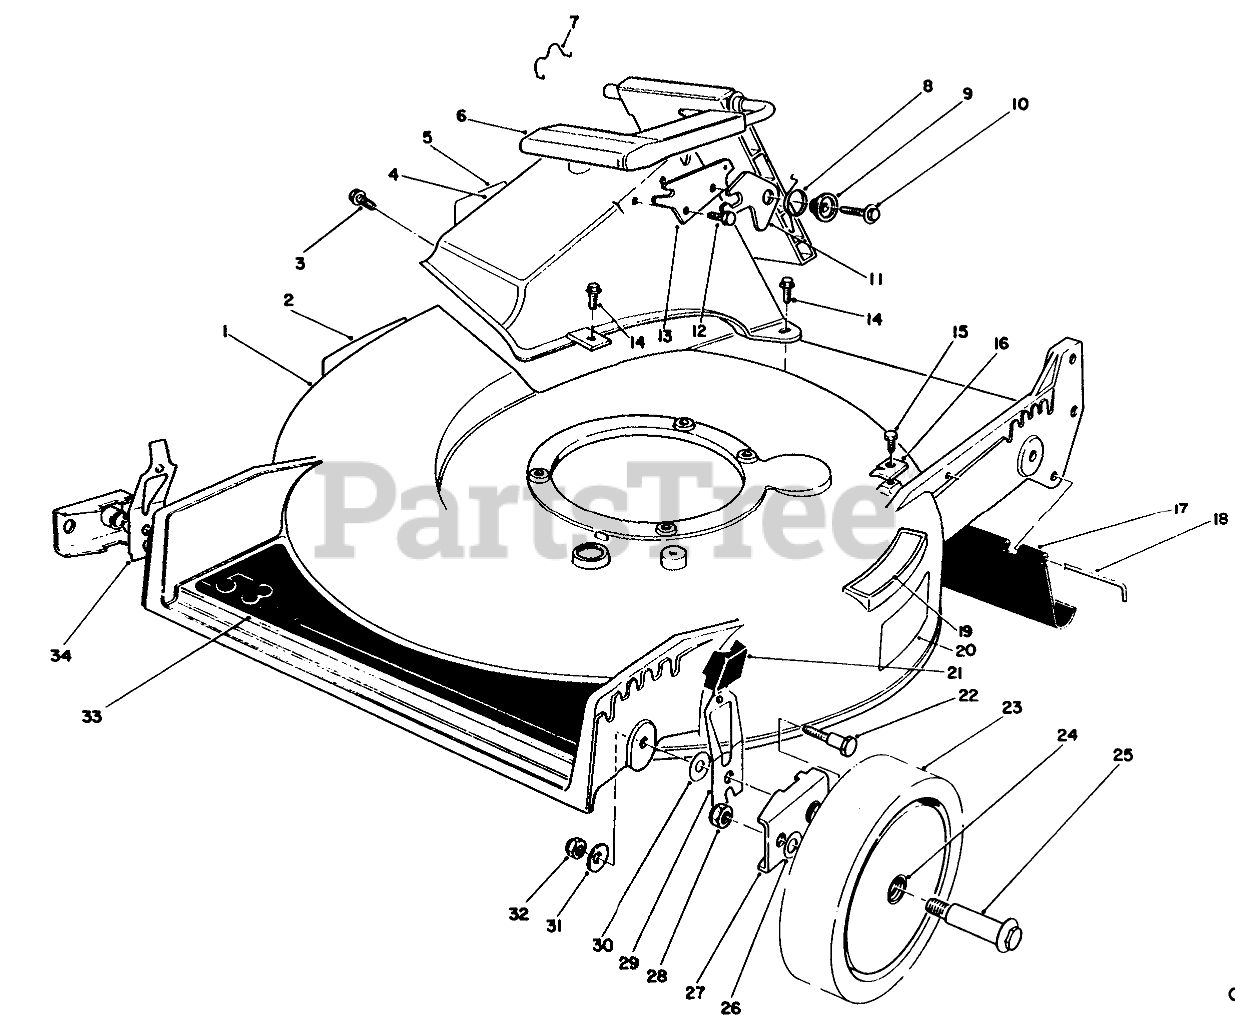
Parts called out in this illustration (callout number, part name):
1	Housing-21" (Incl. Ref. #2, 19, & 20)
2	DECAL-DANGER
3	SCREW AND WASHER ASM
4	Tunnel Discharge
5	DECAL - DANGER
6	Discharge Door Assembly
7	DOOR RET SPRING
8	TORSION SPRING
9	DOOR SPACER
10	SCREW-HWH
11	SAFETY LATCH
12	SCREW-PLASTITE
13	DOOR LATCH PLATE
14	SCREW-HWH
15	SCREW-HWHTF
16	CLAMP-CABLE
17	SHIELD-TRAILING
18	ROD-SHIELD
19	DECAL - STEP PAD INT'L
20	Decal Danger
21	KNOB-ARM
22	PIVOT SCREW
23	Wheel & Tire Assembly (Incl. Ref. #24)
24	BUSHING
25	BOLT-WHEEL
26	WASHER
27	HP PIVOT ARM ASM
28	Nut
29	L. HP SPRING ARM ASM
30	WASHER-PIVOT
31	WASHER-BELLEVILLE
32	NUT-LOCK, NI
33	Decal-53cm
34	R HP SPRING ARM ASM
